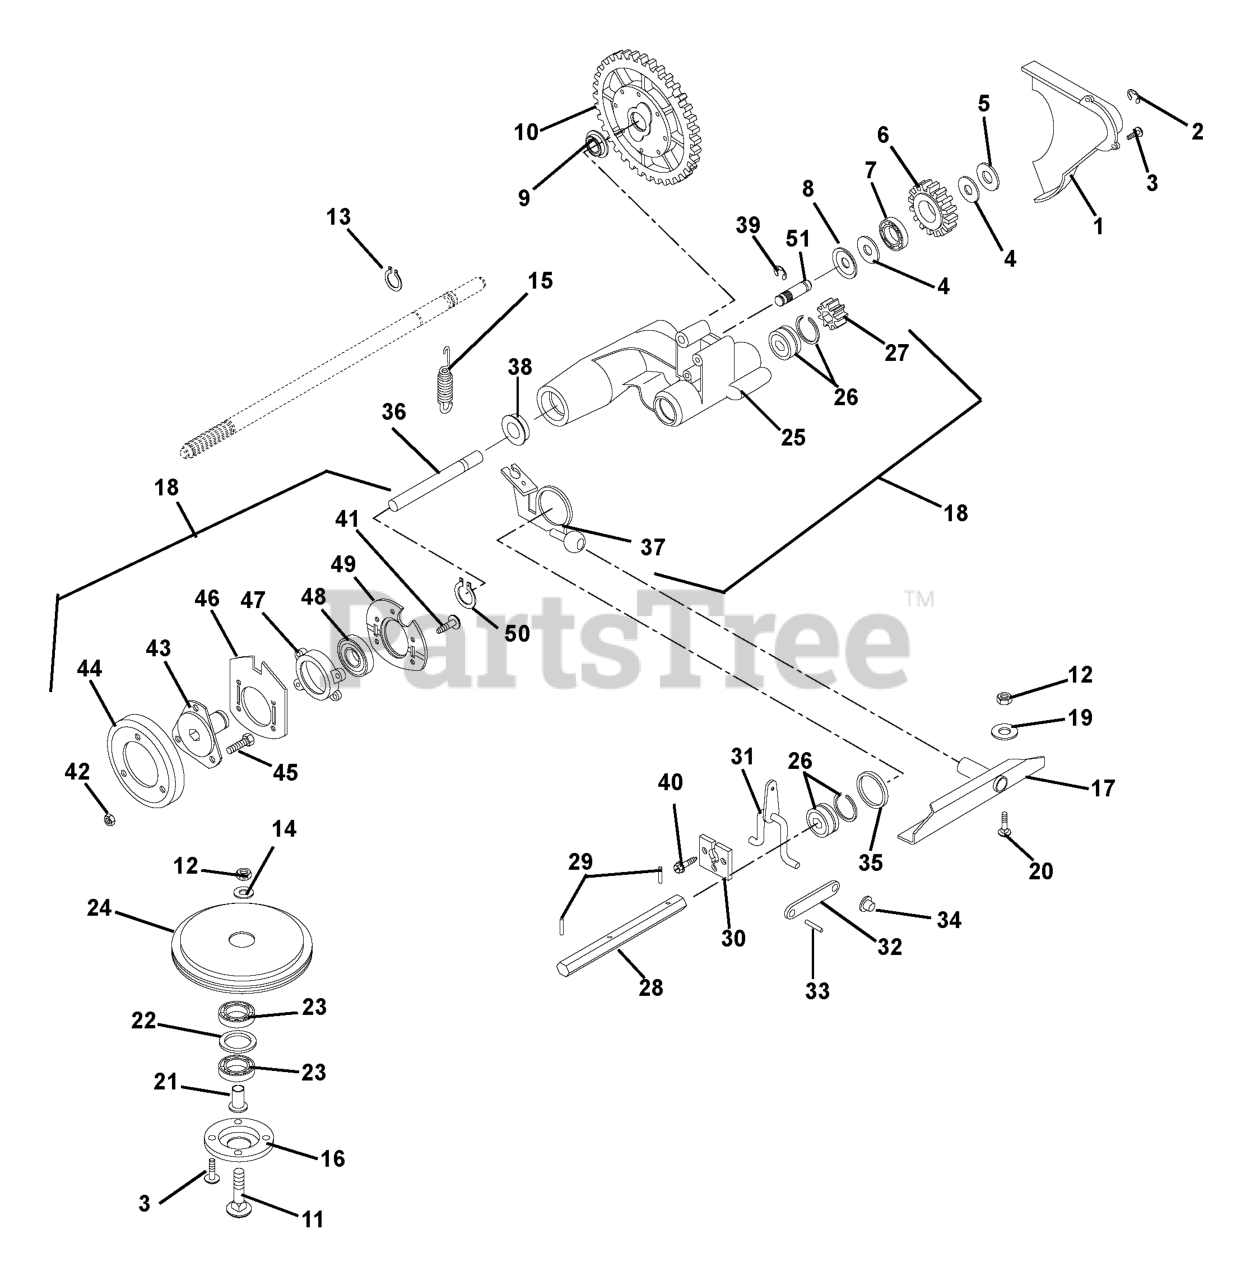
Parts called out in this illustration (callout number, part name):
1	COVER, GEAR
2	RG-RTNG-EXT .438X.035
3	SCR-TAP 12-24X.50 HWH TR YWZC
4	WSHR-FL-STL .52X.827X.062 YWZC
5	WSHR-FL-STL.531X1.00X.063 YWZC
6	IDLER GEAR
7	BRG-BALL .500X1.38X.437
8	RETAINER
9	BRG-BALL .625X1.383X.50
10	DIFFERENTIAL ASSEMBLY
11	BLT-RDHDSQNK .31-18X1.75 G5YZ
12	NUT-LK-CTR .31-18 YWZC
13	RG-RTNG-EXT .579X.035
14	WSHR-FL-STL .328X.87X.179 YWZC
15	SG-TENS .051X.60X2.25 WLD 7.0
16	RETAINER - BEARING
17	PIVOT, CHANNEL WELDMENT
18	KIT, LM DRIVE CARRIER
19	WSHR-FL-STL.344X.688X.065YWZC
20	BLT-RHDSSQNK .31-18X.62 G5YZ
21	SPINDLE - BEARING
22	WSHR-FL-STL 1.062X1.344X.032PL
23	BRG-BALL .625X1.375X.43
24	FRICTION SHEAVE
25	DRIVE CARRIER
26	BRG-BALL .562X1.375X.437
28	SHAFT, HEX
29	PIN-ROLL .188X.88
30	RETAINER PLATE
31	SHIFT ARM WELDMENT
32	SHIFT LINK
33	PIN-ROLL .125X.50
34	PUSH NUT, .25
35	WSHR-FL-STL 1.390X2.00X.020 PL
36	ROD - GUIDE
37	ACTUATOR, WBLM DRIVE
38	BRG-BALL .625X1.383X.50
39	RG-RTNG-EXT .438X.035
40	SCR-TAP 12-24X.50 HWH TR YWZC
41	SCR-TAP 5HX-0.8X16MM H-FL-YWZC
42	NUT-LK-CTR .25-20 YWZC
43	FRICTION WHEEL HUB
44	DISC, FRICTION - 730 MAT'L
45	BLT-HEX .25-20X.50 GR5 YWZC
46	PLATE, BEARING
47	BEARING RETAINER
48	BRG-BALL 1.0X2.0X.56 (1641)
49	BEARING RETAINER
50	RG-RTNG-EXT 1.00X.042
51	IDLER SHAFT
